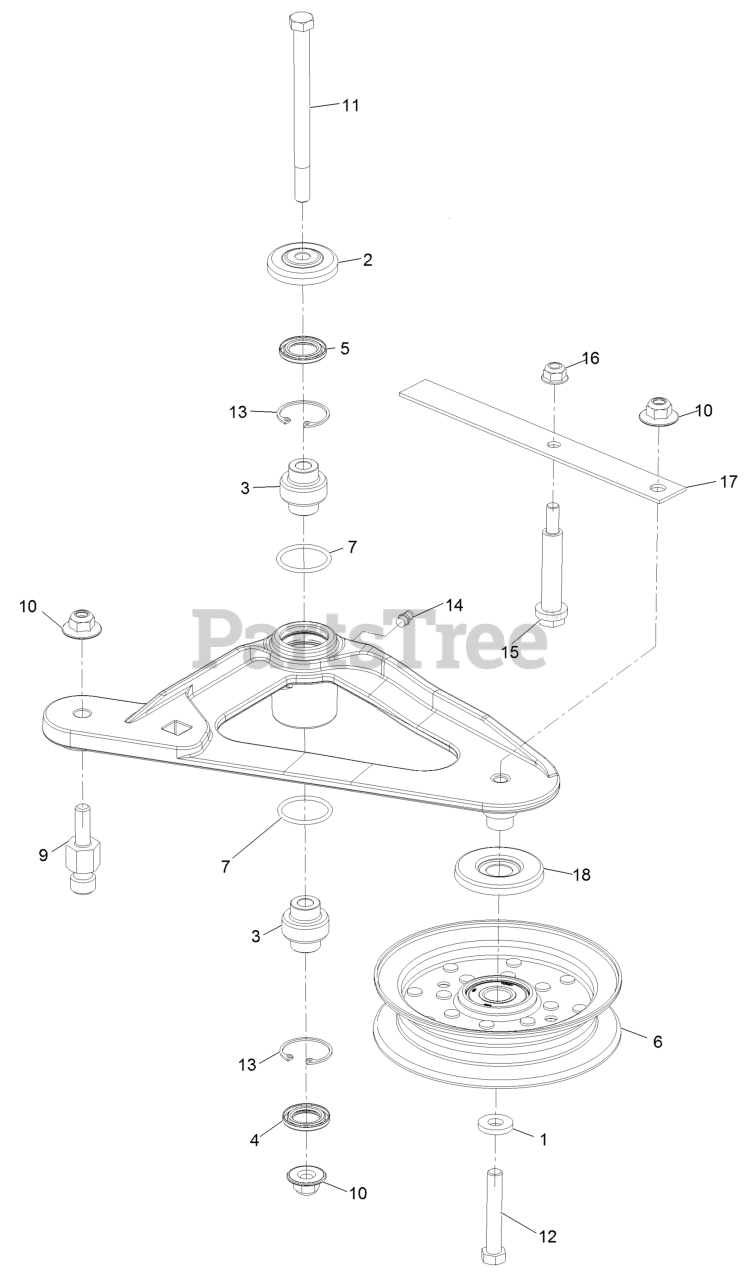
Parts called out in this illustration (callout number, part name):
2	Guard-Top
3	Bearing-Spherical
4	Seal-Double Lip
5	Seal-Single Lip
6	Idler-Pulley, Flat 5.00X0.87
9	Pin-Spring, Anchor
10	Nut-Nyloc 3/8-16 Flg
11	Screw-Shoulder 3/8-16 X 5
12	Screw-HH
13	Ring-Retaining
14	Zerk-1/4-28 Str
15	Screw-Shoulder 5/16-18 X 1 29/32
16	Nut-Nyloc 5/16-18 Flg
17	Spring-Belt Guide Leaf
18	Guard-Dust Shield
